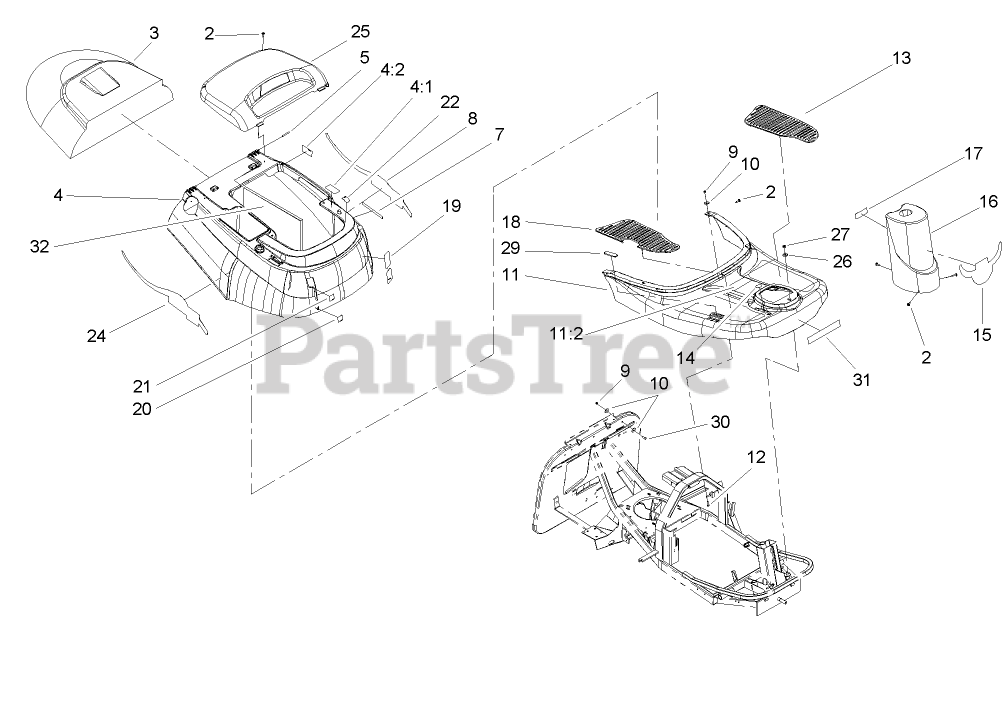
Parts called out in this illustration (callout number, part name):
2	Screw-HH, TAP
3	COVER-GRASS BAG
4	Shroud And Decal ASM
4:1	Decal-Danger
4:2	Loose Parts Package
5	Pin-Dowel
7	Loose Parts Package
10	Washer-Flat
11	FOOT REST AND DECAL ASM
11:2	Loose Parts Package
12	SCREW-HH
13	Floormat-LH
14	Loose Parts Package
15	DECAL-FRONT
16	Steering-Turret
17	Loose Parts Package
18	Floormat-RH
19	Loose Parts Package
20	Loose Parts Package
21	Loose Parts Package
22	Loose Parts Package
25	Cover-Engine
26	Washer-Flat
27	NUT-LOCK
30	SCREW-HH
